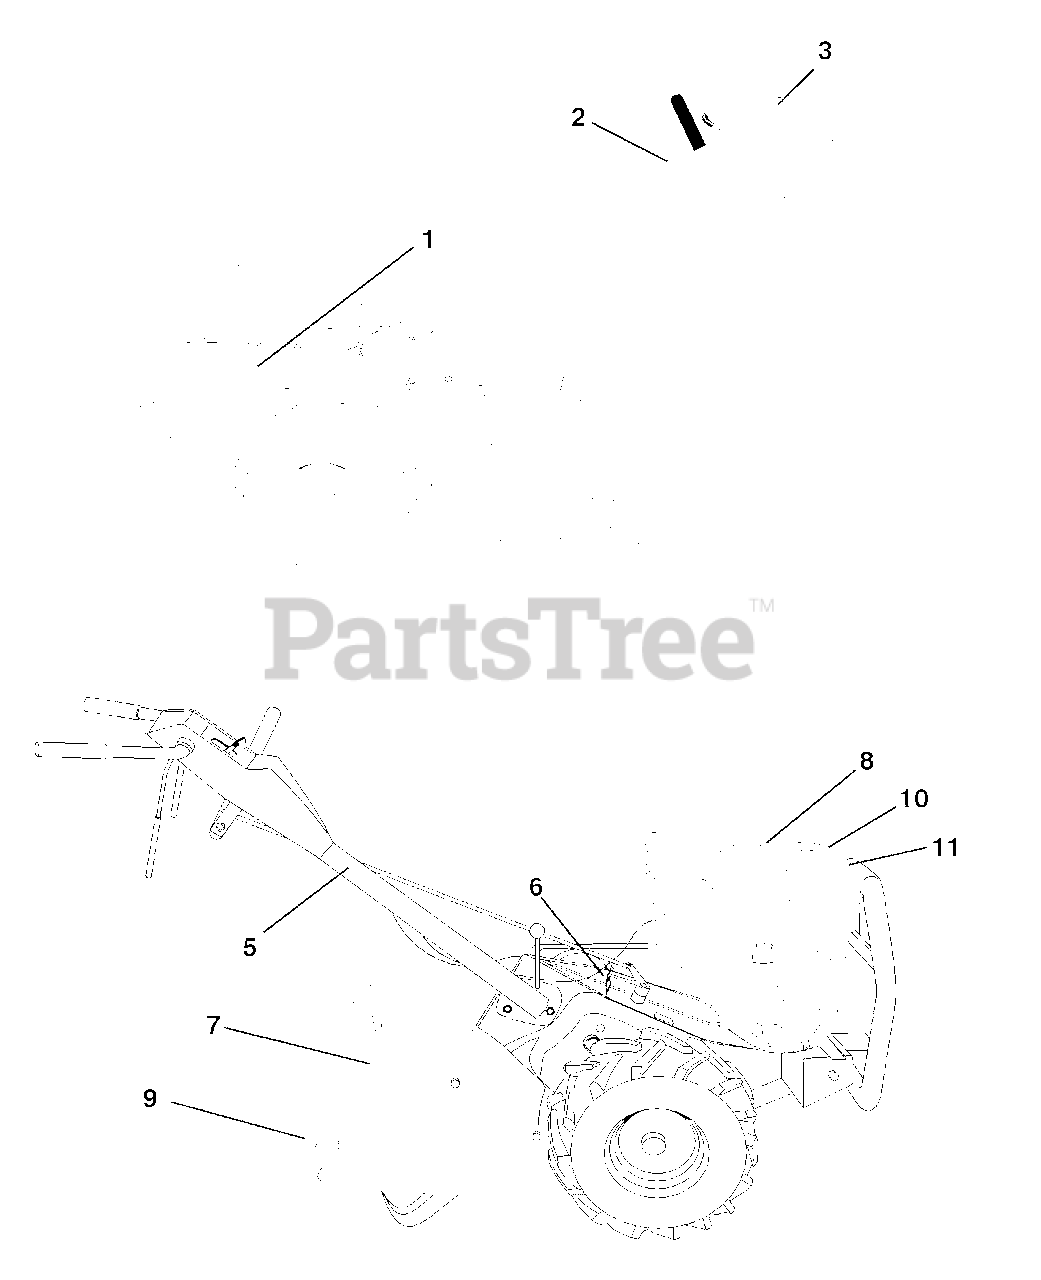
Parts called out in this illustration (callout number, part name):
1	Decal, Logo
2	Decal, Logo
3	Decal, Logo
5	Decal, Hand Placement
6	Decal, Shift Indicator
7	Decal, Warning
8	Decal, Engine HP REF
9	Decal, Warning, Rotating Tines
10	Decal, Engine Intek REF
11	Decal, Engine Choke/Run REF
